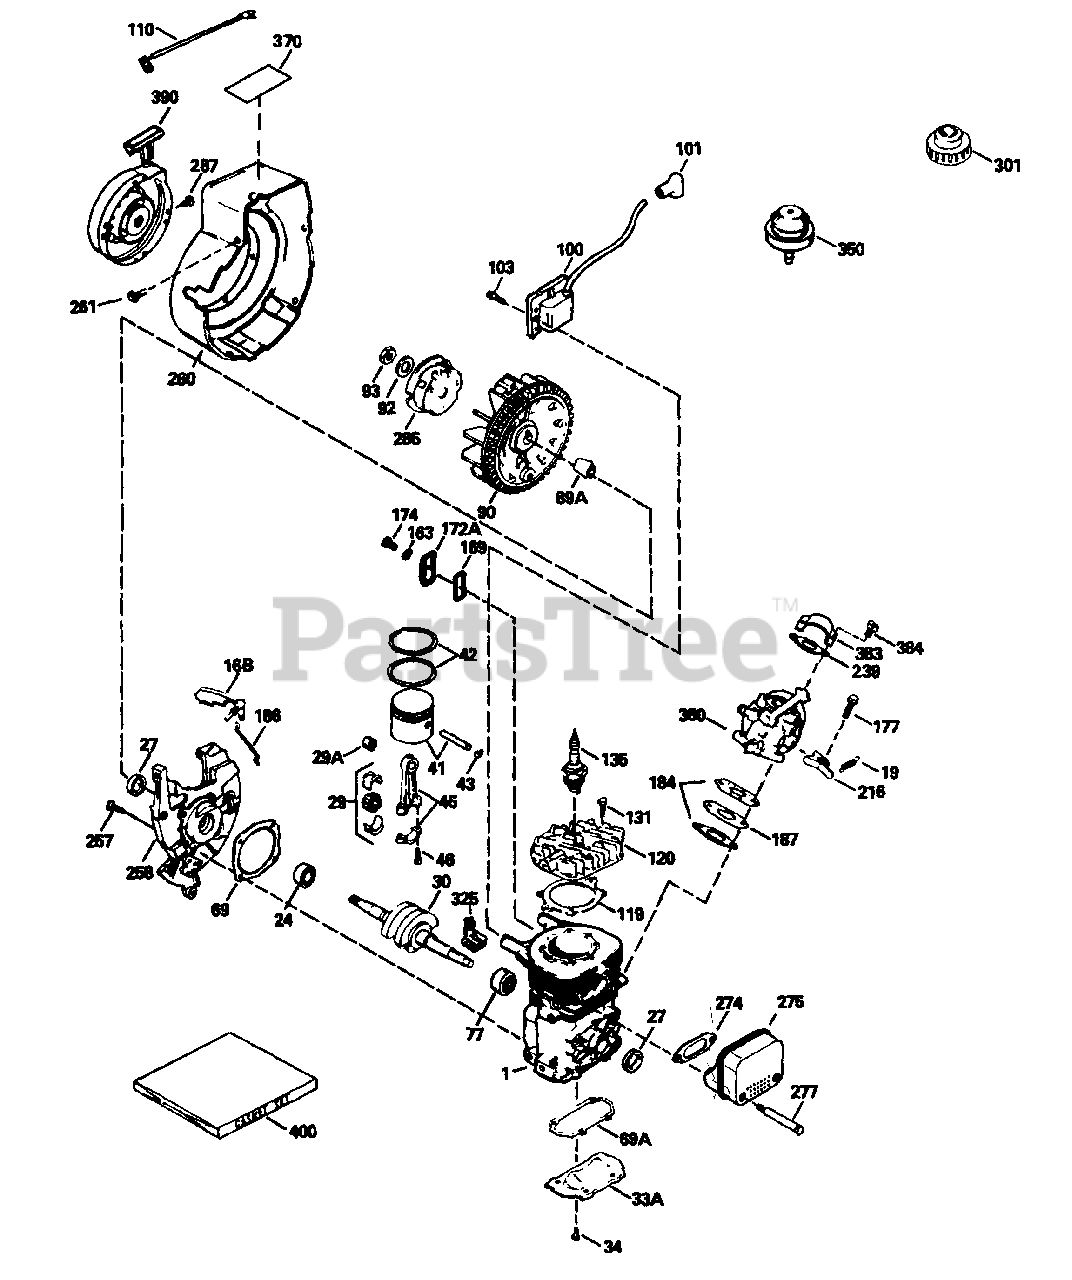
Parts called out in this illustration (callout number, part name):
1	Cylinder (Order S/B if replacement is needed.)
19	Extension Spring
24	Ball Bearing
29	Needle Bearing & Liner Set (37 Needles)
29A	Cartridge Bearing
30	Crankshaft
33A	Cover Plate
34	Screw, Torx T-25, 10-24 x 1/2"
41	Piston & Pin Ass'y.
42	Ring Set
43	Piston Pin Retaining Ring
45	Connecting Rod Ass'y.
46	Connecting Rod Bolt
69	Cylinder Cover Gasket
69A	Cover Plate Gasket
77	Cartridge Bearing
89A	Adapter Sleeve
92	Belleville Washer
93	Flywheel Nut
100	Solid State Ignition
101	Spark Plug Cover
103	Screw, Torx T-15, 10-24 x 1"
110	Ground Wire
119	Cylinder Head Gasket
120	Cylinder Head
131	Screw, Torx T-30, 1/4-20 x 3/4"
135	Resistor Spark Plug
169	Cover Plate Gasket
172A	Compression Release Cover
174	Screw, Torx T-25, 10-24 x 1/2"
177	Screw, 5/32 Allen, 1/4-20 x 1"
184	Carburetor Gasket
186	Governor Link
216	R.P.M. Adjusting Lever
239	Air Cleaner Gasket
257	Screw, Torx T-30, 1/4-20 x 5/8"
258	Blower Housing Base
260	Blower Housing
261	Screw, 1/4-20 x 1/2"
274	Exhaust Gasket
275	Muffler
277	Screw, 1/4-20 x 2-3/4"
285	Starter Cup
287	Screw, 8-32 x 21/64"
325	Wire Clip
350	Primer Ass'y,
370	Instruction Decal
380	Carburetor
384	Screw, Torx T-25, 10-32 x 3/8"
390	Rewind Starter
400	Gasket Set
